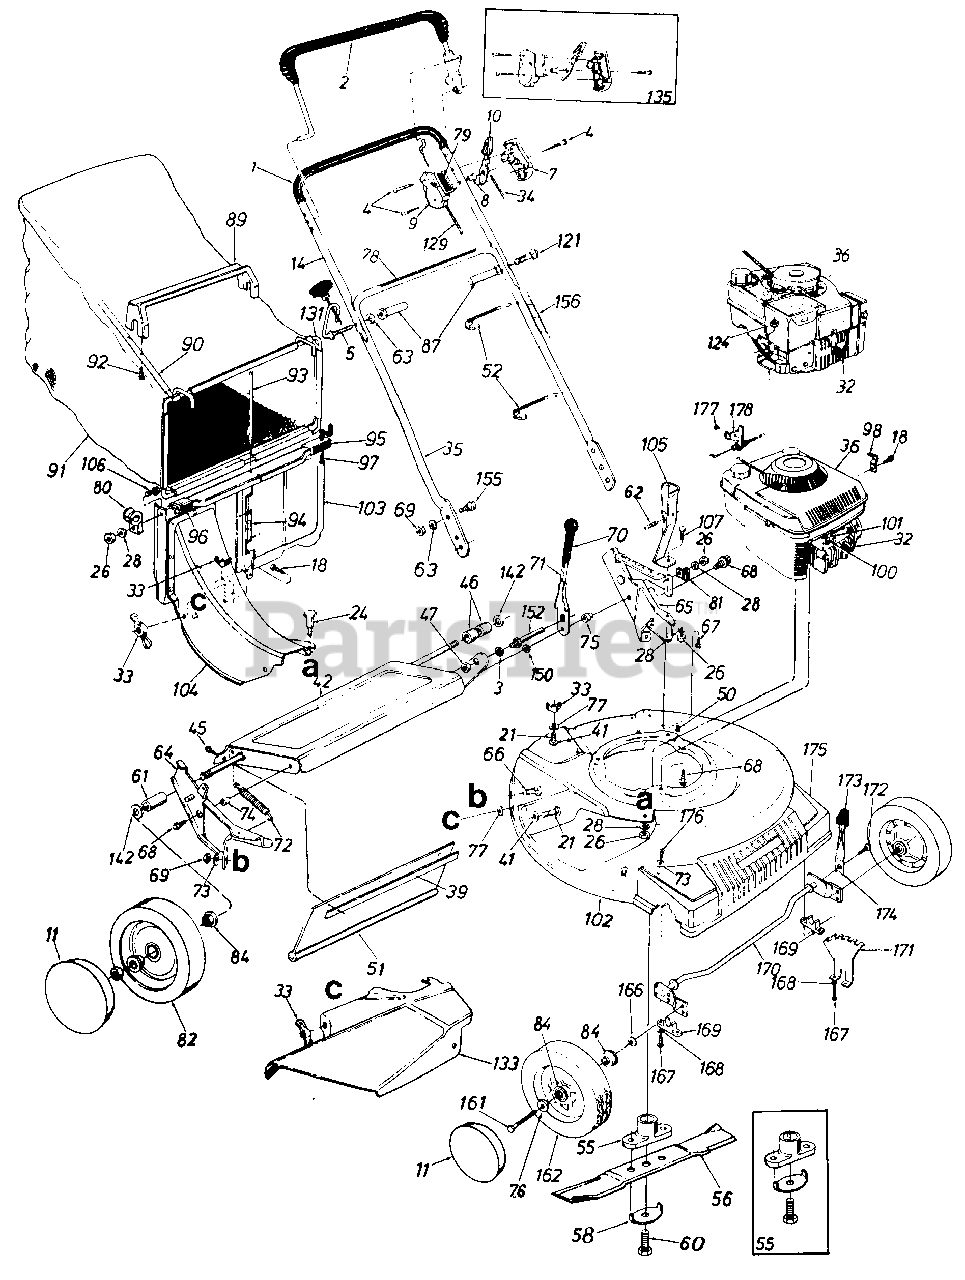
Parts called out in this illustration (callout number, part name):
1	Foam Grip
2	Control Handle Ass'y. L.H.
3	L-Wash. 3/8" I.D.
4	Truss Mach. Scr. #12 x 1.5"
5	Rope Guide Bolt
7	Control Panel Half
8	Control Disc Pin
9	Clutch Panel Half
10	Throttle Control Lever
11	Hub Cap
14	Upper Handle
18	Hex B-Tap Scr. #10 x .38"
21	Carriage Bolt 1/4-20 x .62"
24	Shoulder Bolt .312 Dia. x .18 Lg. Special
26	Hex Nut 1/4-20 Thd.
28	L-Wash. 1/4" I.D.
32	Spark Plug Insulator
33	Wing Nut w/Washer
34	Throttle Control Wire 58"
35	Lower Handle
36	Engine
39	Retaining Strip
41	Fl-Wash. .344" I.D. x .62"
45	Hex AB-Tap Scr. 1/4 x .62"
46	Spacer.526" I.D.
47	Hex Jam Nut 3/8-24 Thd.
51	Rear Flap
52	C able Tie
55	Blade Adapter Kit
56	21" Blade
58	Blade Bell-Wash.
60	Hex Bolt 7/16-20 x 1.5" Grade 5
61	Sleeve.526" I.D.
62	Truss Mach. Scr. 1/4-20 x .75"
63	L-Wash. 5/16" I.D.
64	R.H. Handle Wheel Brkt. Ass'y.
65	L.H. Handle Wheel Brkt. Ass'y.
66	Carriage Bolt 5/16-18 X .62
67	Hex B-Tap Scr. 5/16-18
68	Hex TT-Tap Scr. 3/8-16
69	Hex Nut 5/16-18 Thd.
71	Height Adj. Lever
72	Extension Spring 3.80" Lg.
73	Bell-Wash. 5/16" I.D.
74	Spacer.383" I.D.
75	Shld. Spacer .5" Dia.
76	Fl-Wash. .531" I.D.
77	Bolt Retainer 1/4 x .50" O.D.
78	Instruction Label
79	Control Label
80	Rope Guide
81	Clamp
82	Wheel Ass'y. Comp.
84	Flange Ball Bearing 1/2" I.D.
87	Catcher Support Pin
89	Bag Handle
90	Rear Catcher Frame
91	Grass Bag
92	Hex AB-Tap Scr. #12 x 1.25" Lg.
93	Chute Rod .188" Dia.
94	Torsion Spring
95	Door Clip
96	Panel Clip
97	Hex AB-Tap Scr. 1/4" x .75"
98	Casing Clampt
100	Hex B-Tap Scr. #10 x .62"
101	Casing Clamp
104	Top Discharge Chute Ass'y.
105	Grass Catcher Bracket
106	Truss Mach. Scr. 1/4-20 x .50" Lg.
107	Hex Bolt 1/4-20 x 50" Lg.
121	Curved Carr. Bolt 5/16-18 x 1.75" Lg.
124	Hex Nut 3/8 x 16 Thd.
129	Control Cable 46"
131	Front Catcher Frame
133	Side Chute Deflector Ass'y.
135	Kit Control Housing Comp.
142	Fl-Wash. .510" I.D. x .75"
150	Fl-Wash. 3/8" I.D. x 1.0"
152	Shld. Pin 3/8-24 x 1.43" Lg.
155	Truss Mach. Scr. 5/16-18 x .75"
156	Plastic Tubing
161	Front Axle Bolt
162	Wheel Ass'y. Comp.
166	Bell-Wash. .400" I.D. x .88
167	Hex B-Tap Scr. 1/4-20
168	L-Wash. 1/4" I.D.
169	Block Bushing
170	Axle Ass'y.
171	Height Adj. Bracket
172	Hex TT-Tap Scr. 1/4-20 x .50"
173	Knob
174	Spring Lever
175	Plastic Front End
176	Truss B-Tap Scr. 5/16 x .75"
177	Pop Rivet
178	Cable Bracket
